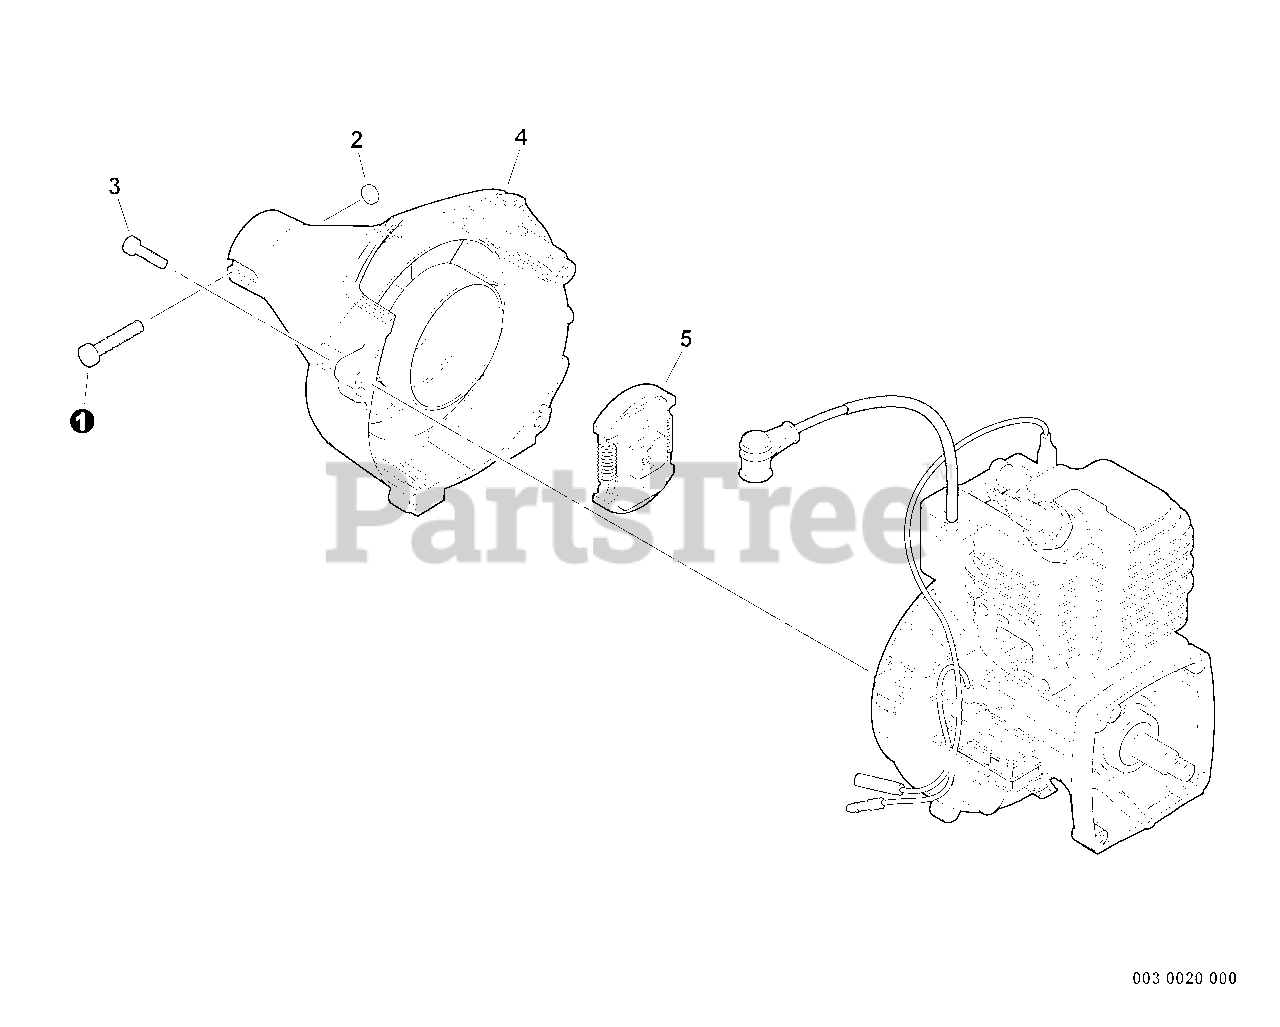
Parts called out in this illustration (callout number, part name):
1	SCREW - 5X25
3	SCREW - 4X16
4	FAN CASE ASSY
5	CLUTCH ASSY
